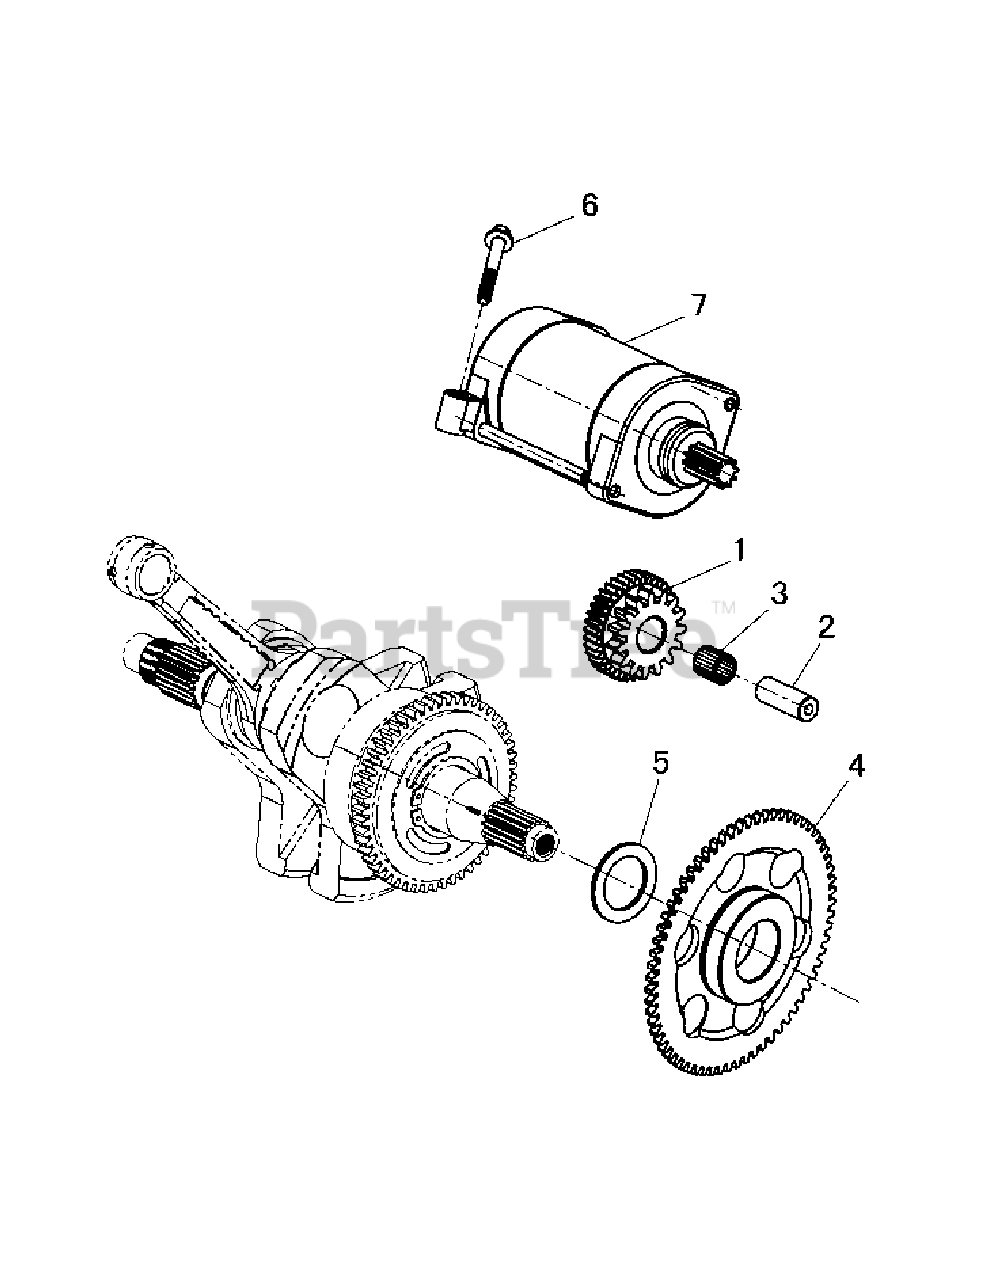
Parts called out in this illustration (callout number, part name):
1	Gear Wheel-Pair
2	Gear Wheel Shaft-Pair
3	Needle Bearing
6	Flangebolt M6X30
7	Starter-Utv Comp
